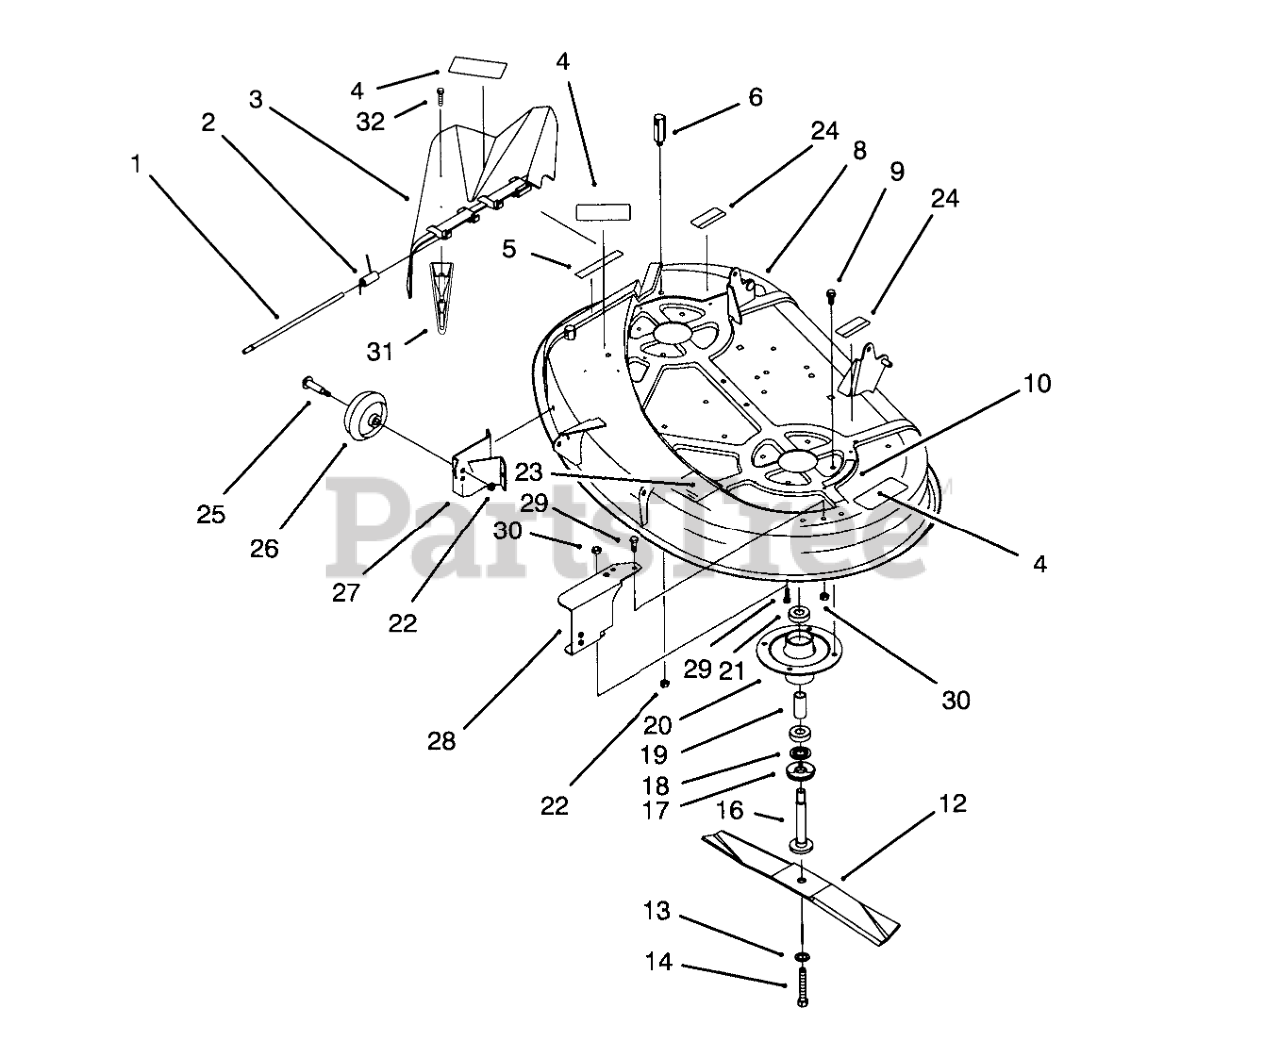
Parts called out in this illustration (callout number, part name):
1	ROD-HINGE DEFLECTOR
2	SPRING
3	Deflector Assembly (Incl. Ref. #4)
4	DECAL-DANGER
5	DECAL-DANGER
6	REAR PIVOT POST (PLTD)
8	Deck-38"
9	SCREW-TAPTITE
10	DECAL-DANGER, SHIELD
12	Blade
13	WASHER-BELLEVILLE
14	SCREW-HH
16	SHAFT-SPINDLE
17	SHIELD-BEARING
18	SPACER
19	SPACER
20	HOUSING-SPINDLE
21	BEARING-BALL
22	NUT-LOCK, NI
23	DECAL-ROUTING, BELT
24	DECAL-WARNING
25	SCREW-SHOULDER, HWH
26	WHEEL-GAGE
27	Bracket-R.H.
28	LH WHEEL DECK BRKT
29	SCREW-HH
30	NUT-LOCK, NI
31	KICKER
32	SCREW-PPH
